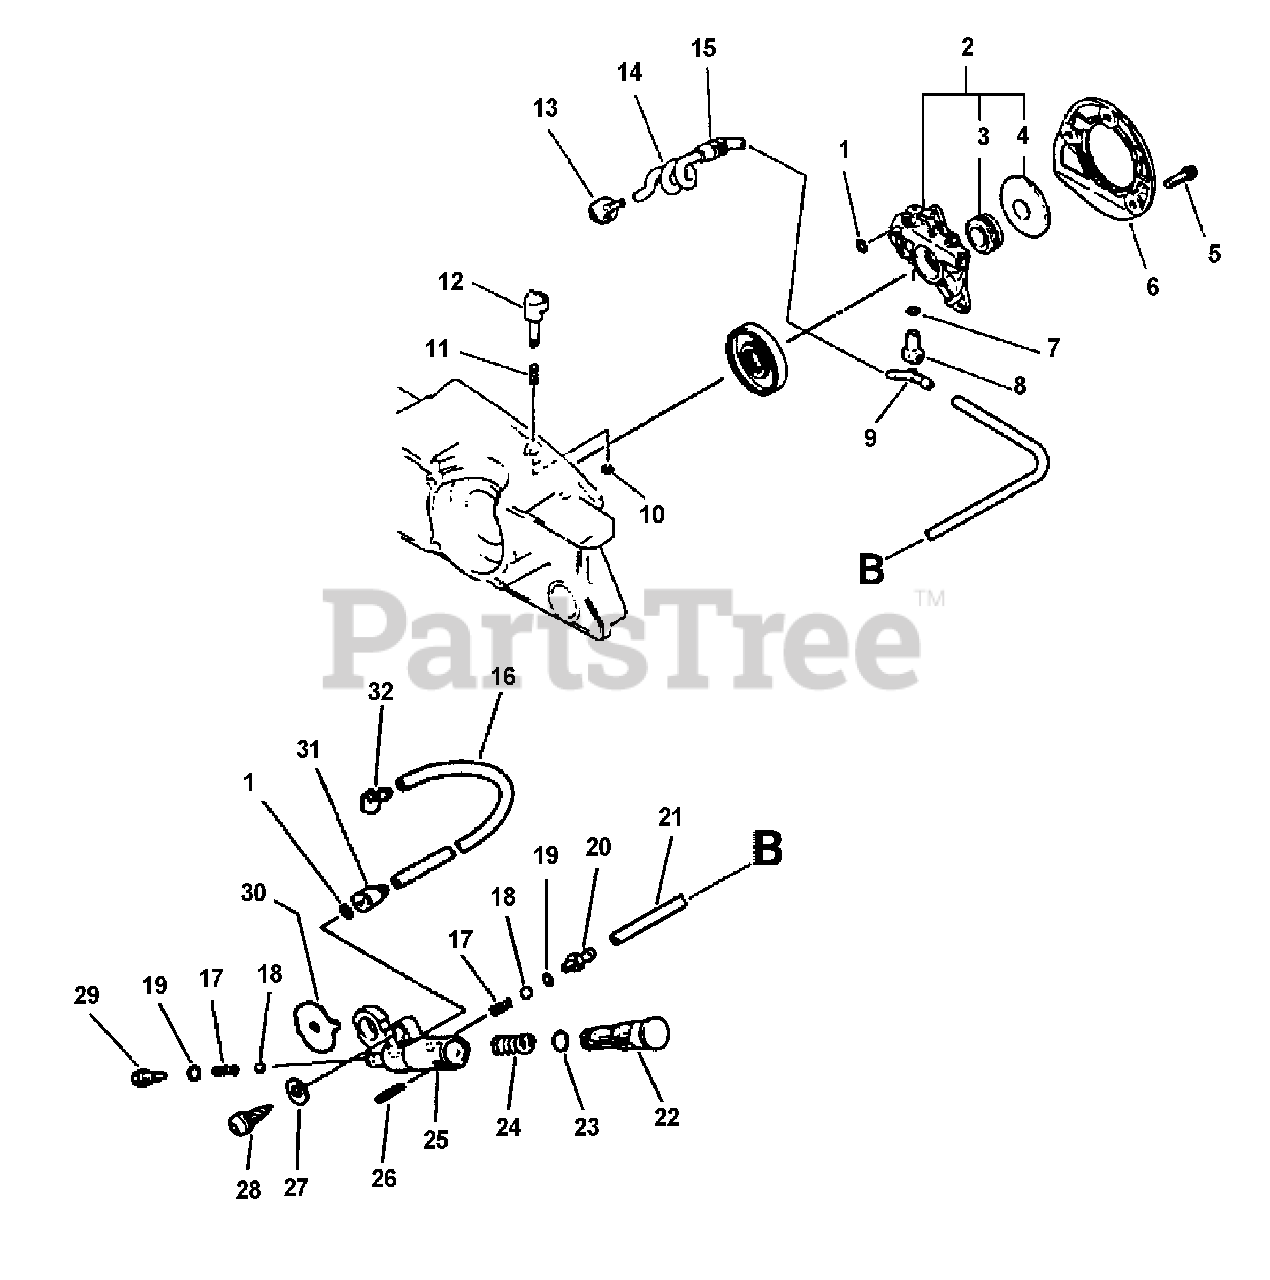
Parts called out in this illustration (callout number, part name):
1	O-RING - 3
2	AUTO-OILER ASSY
3	GEAR - WORM
4	WASHER - 12
5	SCREW - 4X12
6	COVER, OIL PUMP
7	CLIP - 6.5
8	CONNECTOR, PIPE
9	PIPE - 3X6X20 -- BLACK
10	RING, RETAINING - 3
12	DIAL, AUTO-OILER
13	FILTER, OIL
14	PIPE - OIL
15	OIL PUMP ASSY
16	PIPE, OIL - 3X6X125
17	SPRING, VALVE
18	VALVE, BALL
21	PIPE - OIL
22	PISTON, OIL PUMP
23	O-RING - 7
25	BODY, OIL PUMP
26	PIN - SPRING -- 2X16
27	WASHER - 5
28	SCREW - 5X20
29	ADAPTER, OIL PUMP
30	BRACKET, OIL PUMP
31	CONNECTOR, PIPE
32	CONNECTOR, PIPE
